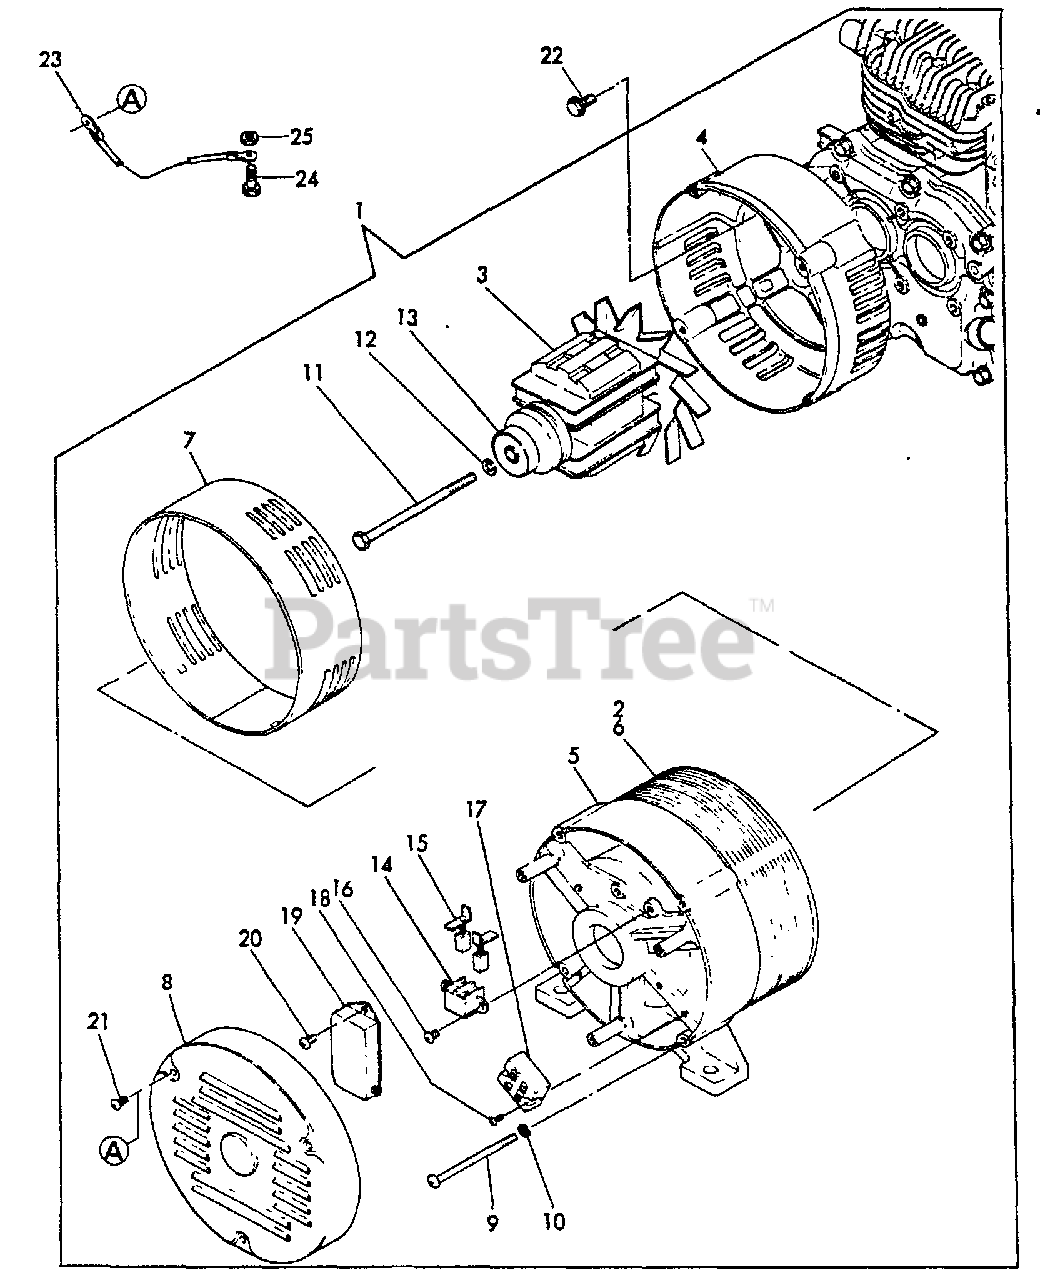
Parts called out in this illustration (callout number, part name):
1	GENERATOR 3.8KVA
2	STATOR ASSY
3	ROTOR ASSY
4	COVER, FRONT
5	COVER - REAR
6	STATOR
7	BAND
8	COVER, END
9	BOLT, THROUGH
10	LOCKWASHER - 6
11	BOLT
12	LOCKWASHER - 10
13	BEARING, BALL
14	HOLDER, BRUSH
15	BRUSH
16	SCREW - 4×10
17	TERMINAL
18	SCREW - 5×14
19	A.V.R.
20	SCREW - 5×14
21	SCREW - 4×10
22	BOLT - 8×20 -- PLATED
23	WIRE, EARTH
24	BOLT - 6×16 -- PLATED
25	LOCKNUT - 6 -- PLATED
